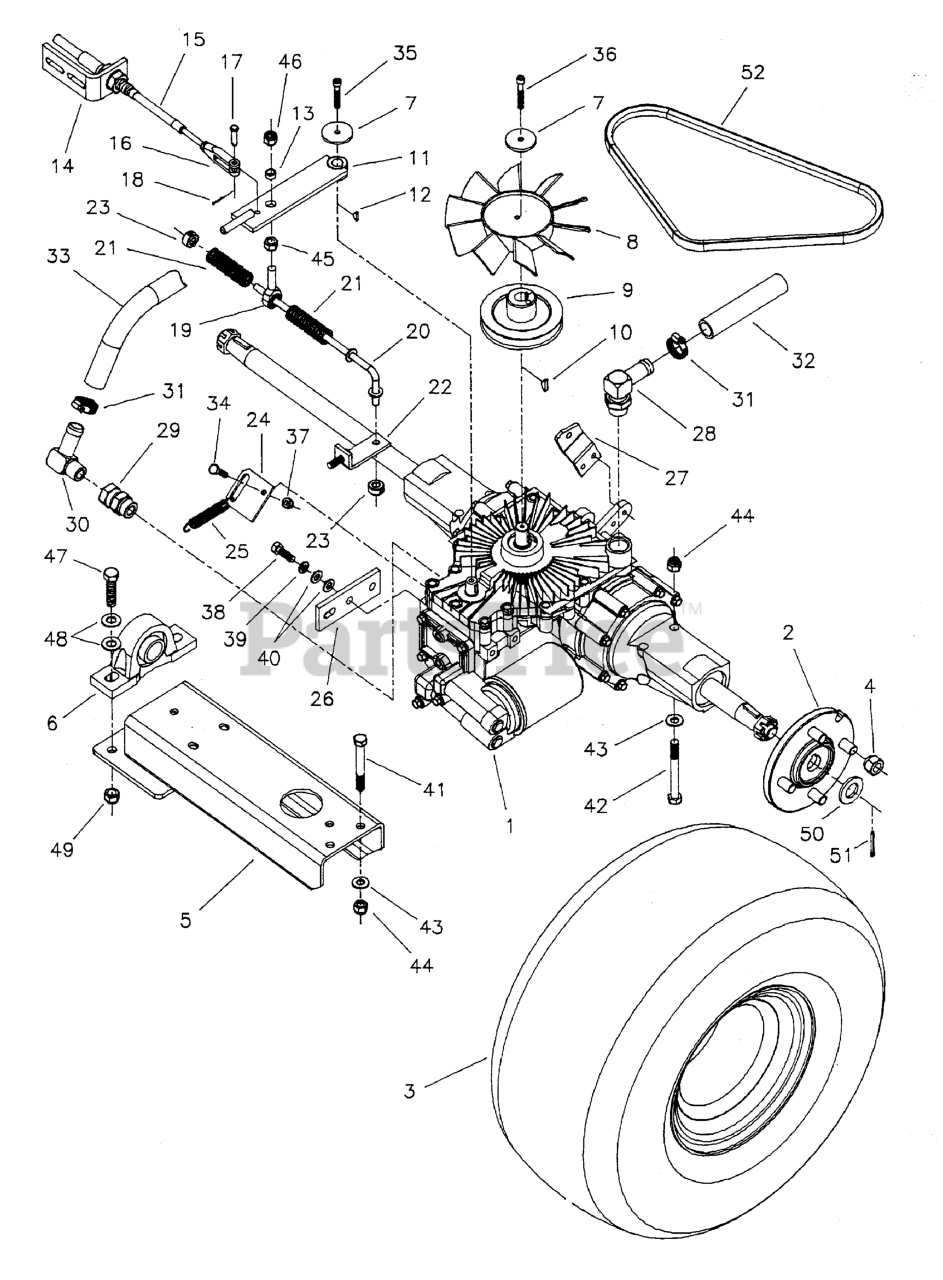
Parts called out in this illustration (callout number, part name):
1	TRANSMISSION
2	HUB, 4-Bolt Tapered
3	WHEEL & TIRE ASSEMBLY, 20 x 10 x 8, Complete
4	LUG NUT, 1/2-20
5	AXLE SUPPORT
6	BEARING, PILLOW BLOCK, 1
7	WASHER, .265 x 1.50 x .109
9	PULLEY, Transmission Input
10	KEY, Hi-Pro Woodruff
11	TRANSMISSION CONTROL ARM
12	KEY, #3 Woodruff
13	SPACER, .38 x .50 x .27
14	CABLE BRACKET
15	CABLE, Speed Control
17	CLEVIS PIN, 1/4 x 1
18	COTTER PIN, 1/16" x 1/2"
19	BALL JOINT, 3/8-24 Male
20	ROD, NEUTRAL SPRING WELDMENT
21	SPRING, Compression
22	Spring Anchor
23	COLLAR, 5/16" Set
24	DUMP VALVE LEVER
25	SPRING, Extension
26	BRACKET, Transmission Support
27	BRAKE LEVER
28	FITTING, 90 Degrees 7/8" O-Ring
29	FITTING, 7/8" O-Ring Straight Swivel
30	FITTING, 90 Degrees 1/2" NPT
31	CLAMP, #10 Hose
32	Transmission Inlet Hose, 4.875" Long
33	HOSE, Transmission Return, 14.75"
34	BOLT, 1/4-20 X 1" GD5 CZ
35	BOLT, Allen Head, 1/4-20 x 1-1/2
36	BOLT, Allen Head, 1/4-20 x 1-3/4
37	NUT, 1/4-20 HEX NYLON LOCK
38	BOLT, 5/16-18 X 1 GD5 YZ
39	WASHER, 5/16 LOCK CZ
40	WASHER, 5/16" SAE
41	BOLT, 3/8-16 X 3" GD5 CZ
42	BOLT, 3/8-16 X 3-1/2" GD5 CZ
43	WASHER, 3/8" GD9
44	NUT, 3/8-16 HEX NYLON LOCK
45	NUT, 3/8-24 Hex
46	NUT, 3/8-24 Hex Nylon Lock
47	BOLT, 7/16-20 X 1-3/4" GD.5
48	WASHER, 7/16" SAE
49	NUT, 7/16-20 Hex Nylon Lock
50	WASHER, 3/4 SAE
51	PIN, COTTER, 1/8 X 1-1/4
52	BELT, A-Section
